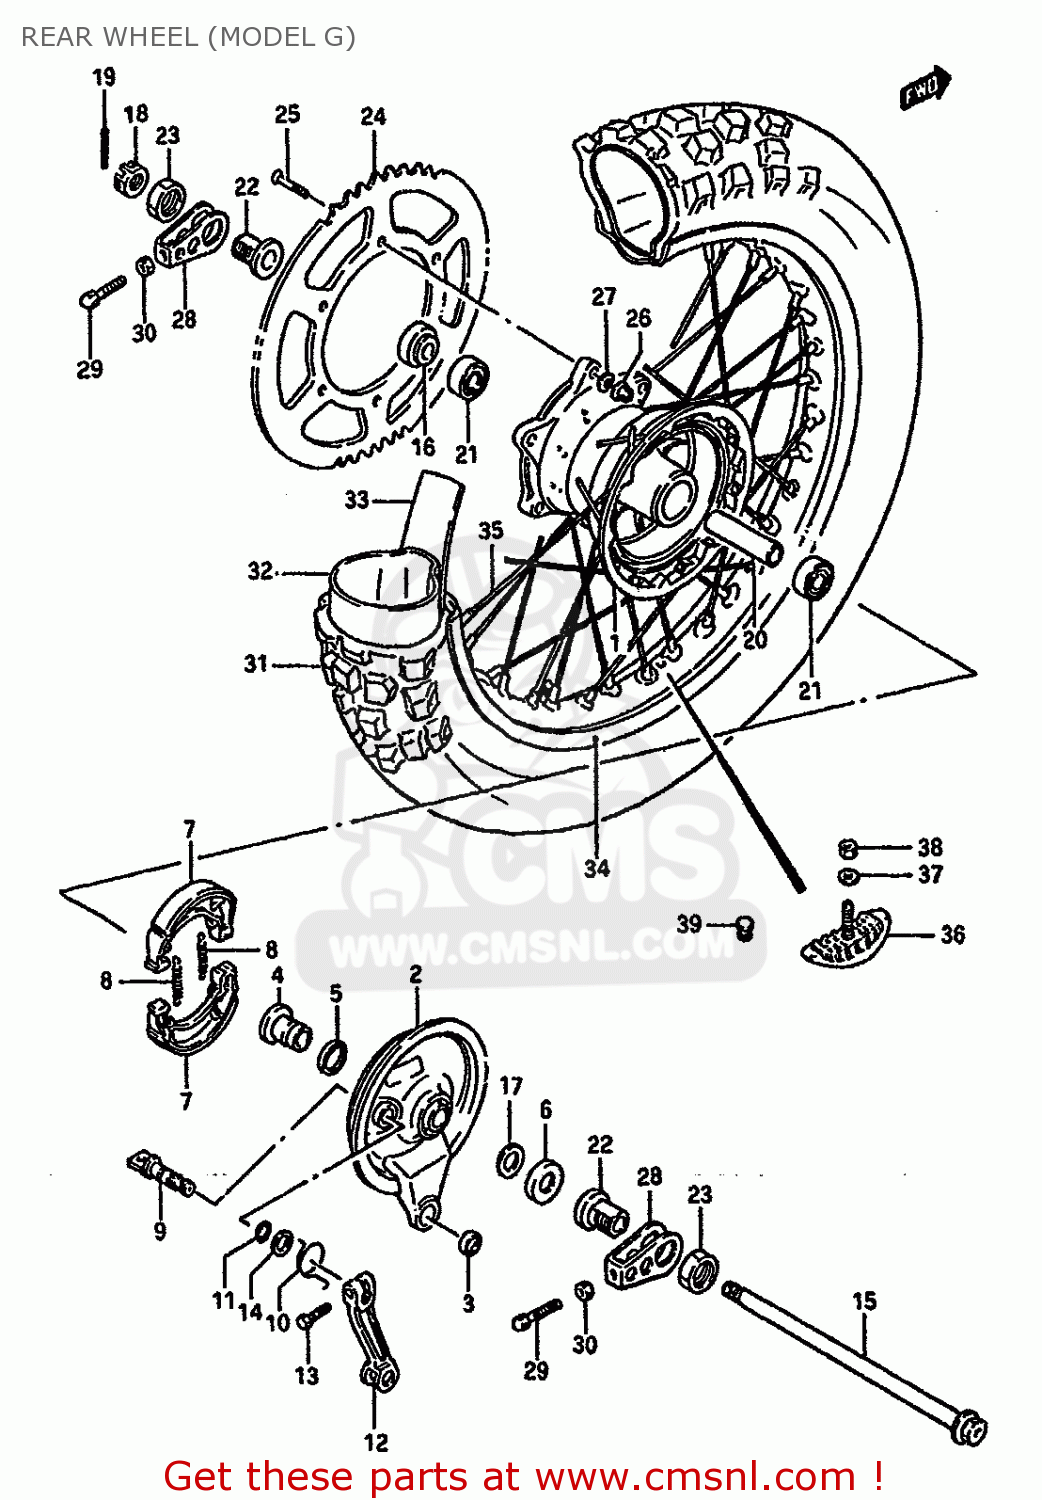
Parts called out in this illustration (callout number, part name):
1	HUB,REAR WHEEL
2	PANEL SET,REAR
3	BEARING
4	SPACER,RR BR AHR PNL
5	SEAL,OIL(20X27X5)
6	CVR,RR BRAKE AHR PNL DUST SEAL
7	SHOE,BRAKE (MCA)
8	SPRING(L:34)
9	CAM,FR BRAKE
10	SPRING
11	O RING(D:2.5,ID:11.4)
12	LEVER,REAR BRAKE CAM
13	BOLT
14	WASHER(12.5X20X1)
15	AXLE,REAR
16	SPACER,RR AXLE,L
17	WASHER,THRUST
18	NUT
19	COTTER PIN
20	SPACER,REAR HUB BEARING
21	BEARING(15X35X11)
22	SPACER,CHAIN ADJUSTER
23	NUT
24	SPROCKET,REAR
25	SCREW(8X33.5)
26	NUT
27	WASHER
28	ADJUSTER,CHAIN
29	BOLT(8X43)
30	NUT
31	TIRE
32	TUBE ASSEMBLY,WHEEL,INNER
33	PROTECTOR
34	RIM,REAR WHEEL
35	SPOKE SET,RR WHEEL
36	STOPPER,BEAD
37	WASHER
38	NUT 8MM
39	CAP(OD:12)
